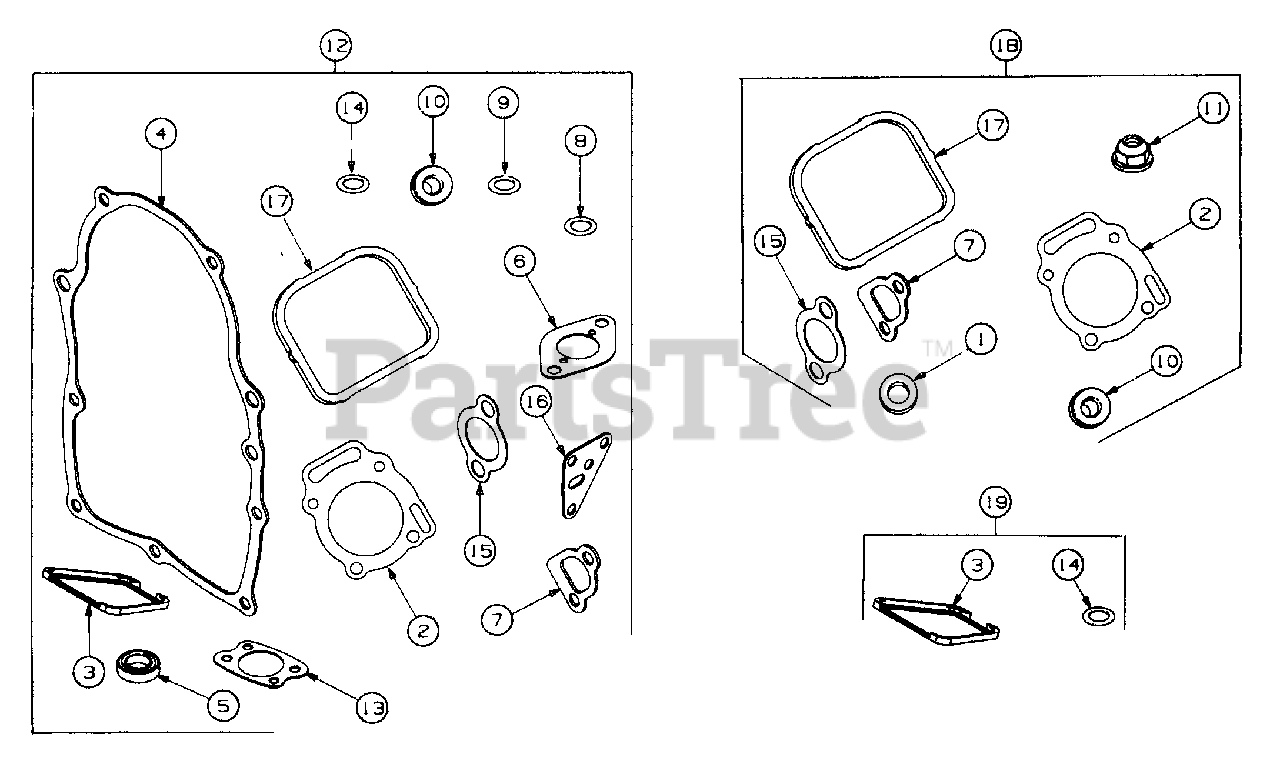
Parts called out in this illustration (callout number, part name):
1	Washer, Cylinder Head
2	Gasket, Cylinder Head
3	Gasket, Breather
4	Gasket, Crankcase Cover
5	Seal, Oil
6	Gasket, Carburetor Mtg
7	Gasket, Intake Manifold
8	O-Ring (Oil Pump)
9	O-Ring (Crankcase Cover)
10	Washer, Valve Cover
11	Nut, Nylock
12	Gasket Set
13	Gasket, Air Cleaner
14	Seal, Breather Screw
15	Gasket, Exhaust Manifold
16	Gasket, Oil Filter Adapter
17	Gasket, Valve Cover
18	Overhaul Kit, Valve
19	Gasket Set, Breather
